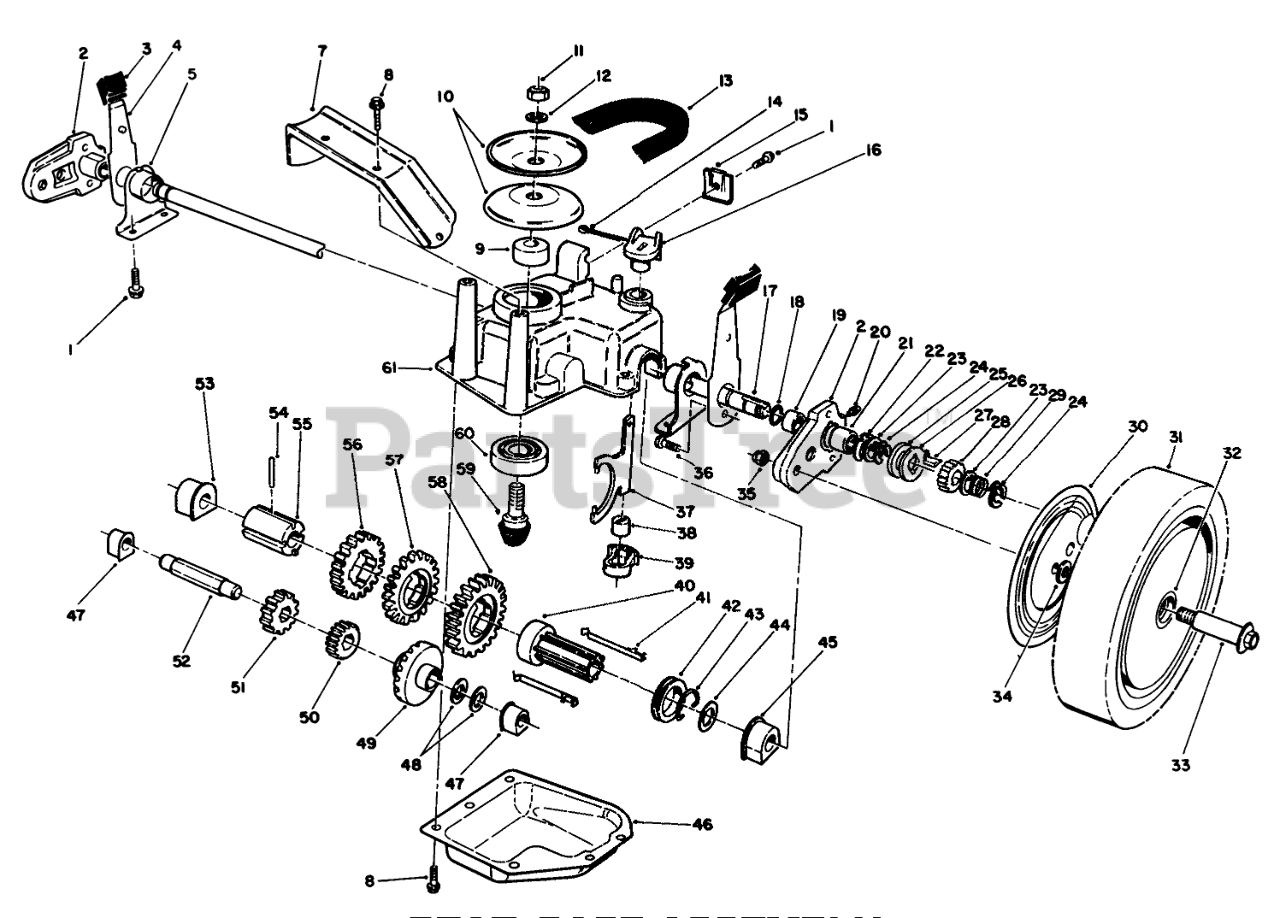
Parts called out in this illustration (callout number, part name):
1	SCREW-HWHTF
2	Pivot Arm Assembly (Incl. Ref. #19-21)
3	KNOB-ARM
4	SPRING ARM ASM
5	CAP-END
7	Bracket-BeltGuide
8	SCREW-HWHTF
9	SPACER
10	Pulley Half
11	NUT-HEX
12	WASHER-FLAT
13	V-BELT
14	PIN-COTTER
15	CABLE CLAMP
16	Lever-Shift
17	SHAFT-OUTPUT
18	O-RING
19	BUSHING
20	FITTING-GREASE
21	BEARING-ROLLER
22	WASHER-ARM, PIVOT
23	WASHER-THRUST, KEYED
24	RING-CLIP, LOCKING
25	RING-FRICTION
26	WASHER-CLUTCH
27	KEY-ROCKING, LH
28	GEAR-PINION
29	SPRING-COMPRESSION
30	WHEEL COVER
31	Wheel Tire & Gear Assy. (Incl. Ref. #32)
32	BUSHING
33	WHEEL BOLT
34	WASHER
35	Nut
36	SCREW-HSH, THREAD FORMING
37	YOKE-SHIFT
38	BUSHING-YOKE
39	RETAINER-FORK, SHIFT
40	Sleeve-Shift Key
41	SHIFT KEY
42	SHIFT COLLAR
43	CLIP-SPRING
44	WASHER-PLAIN
45	BUSHING-OUTPUT
46	Cover-Gearcase
47	BUSHING
48	WASHER-THRUST
49	Gear-Bevel
50	PINION-20T
51	PINION-25T
52	SHAFT-INTERMEDIATE
53	BUSHING
54	PIN-SPRING
55	SLEEVE-GEAR
56	GEAR-39T
57	GEAR-44T
58	GEAR-49T
59	Gear-Pinion
60	BEARING-BALL
61	CASE-GEAR, UPPER
